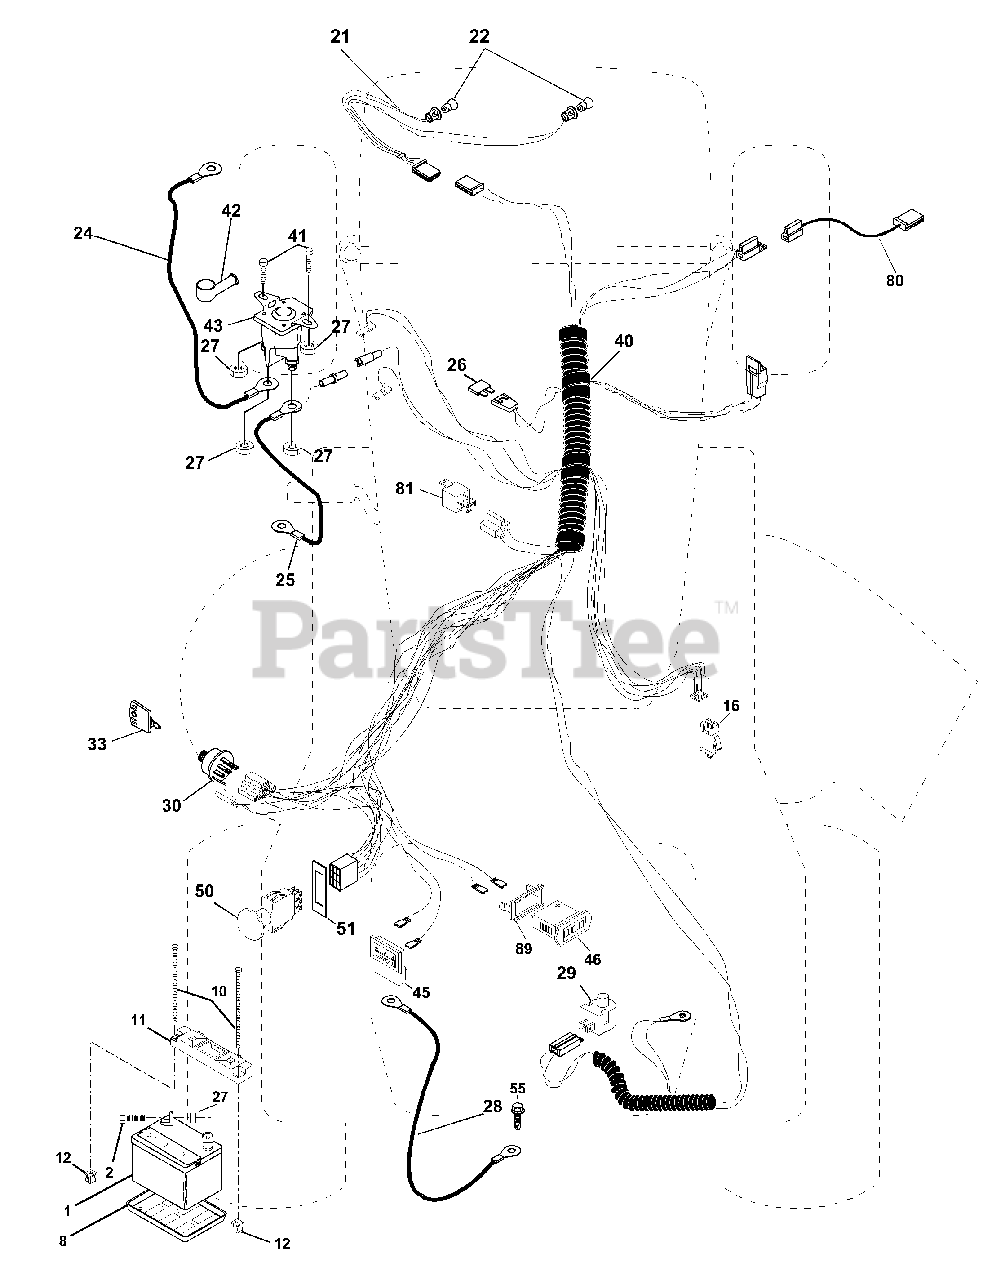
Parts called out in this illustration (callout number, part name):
1	Battery 12 Volt 35 AMP
2	Bolt Hex Hd 1/4-20unc X 3/4
8	Tray Battery
10	Bolt Brt Frt 1/4-20 x 75 Ainc
11	Holddown Battery Front Mount
12	Nut Push Nylon 1/4" Battery Frt
16	Switch Interlock Push-In
20	Nut Jam Hex 1/4-20 Unc
21	Harness Asm Light W/4152j
22	Bulb Light #1156
24	Cable Battery 6 Ga 11" red
25	Cable Battery 6 Ga 22" red w/16 wire
26	Fuse 15 AMP
27	Nut Keps Hex 1/4-20 Unc
28	Cable Ground 6 Ga 21" black
29	Switch Plunger Nc Gray
30	Switch Ign
33	Key Ign Molded Generic
40	Harness Ign.
41	Bolt Blk Fin Hex 1/4 - 20 x 1/2
42	Cover Terminal Red
43	Solenoid
45	Ammeter Rectangular 15 Amp
46	Meter Hour
50	Switch PTO 3 PDT Black Delta
51	Ring Retainer TTO
55	Screw Thdrol 5/16-18 x 1-1/2 Tyt
80	Harness Clutch Evx
81	Relay Asm.
89	Bracket Snap-In Hourmeter
